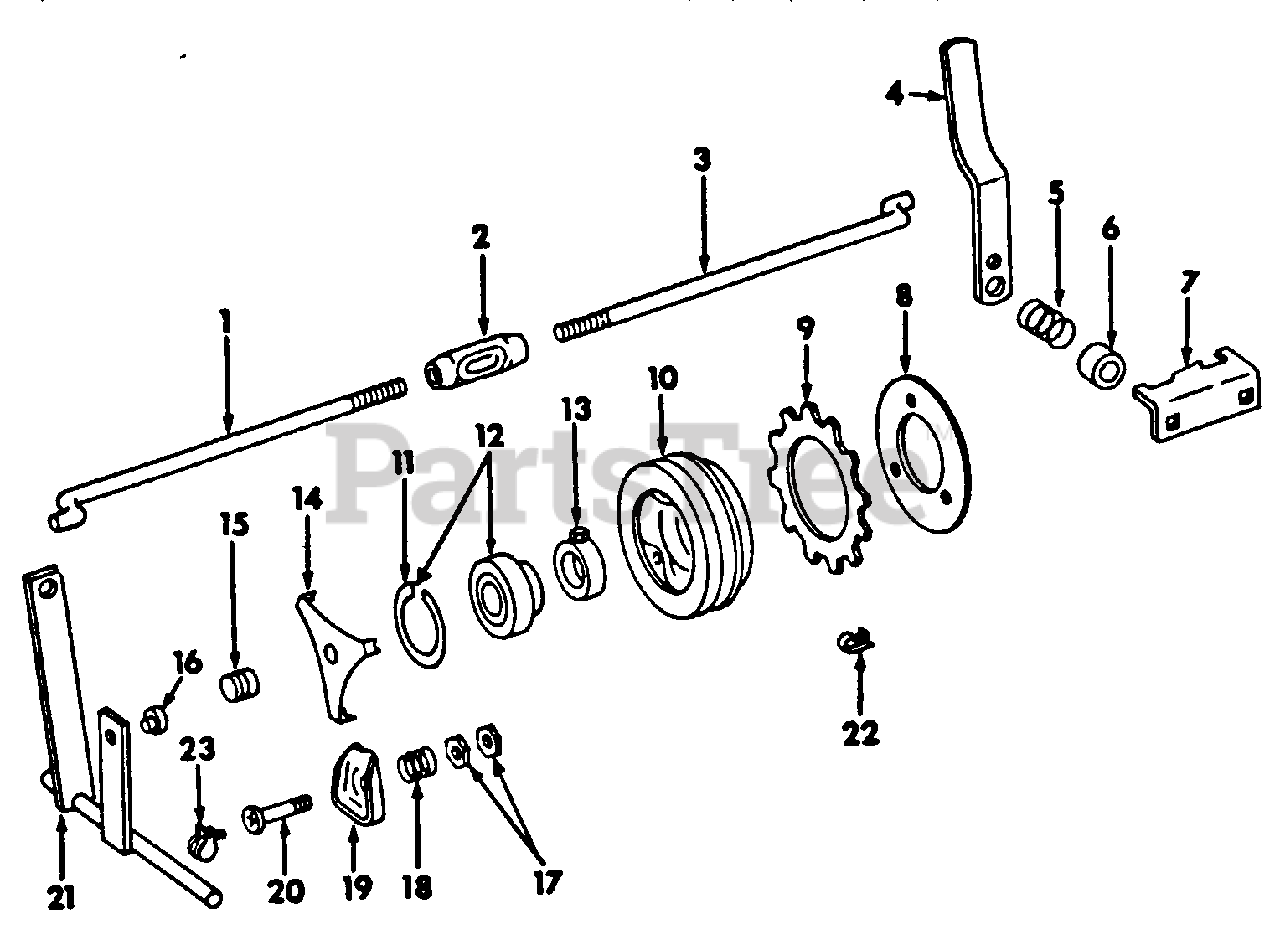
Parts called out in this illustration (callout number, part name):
1	Rod, Clutch
2	Turnbuckle, Rod
3	Rod, Rear Clutch
4	Lever, Handle -Replaces 473 485 R2
5	Spring, 15 Ga Compression -Cub Cadet 70, 71 & 100 Tractors
6	Spacer, Spring -Cub Cadet 70, 71 & 100 Tractors
7	Latch, Handle
8	Plate, Pressure
10	Pulley, Mower Actuating -Replaces 473 474 R1
11	Ring, Bearing Snap
12	Bearing w/Snap Ring, Ball
13	Collar w/Set Screw & Lock Nut, Brg
15	Button, Thrust
16	Button, Wear
17	Nut, 1/4-28 Hex Jam
18	Spring, Compression
19	Lever, Throw-Out
20	Screw, Special Machine
21	Shaft w/Button 478 483 R1, Clutch
22	Spring, Friction Disc
23	Clamp, Locating
